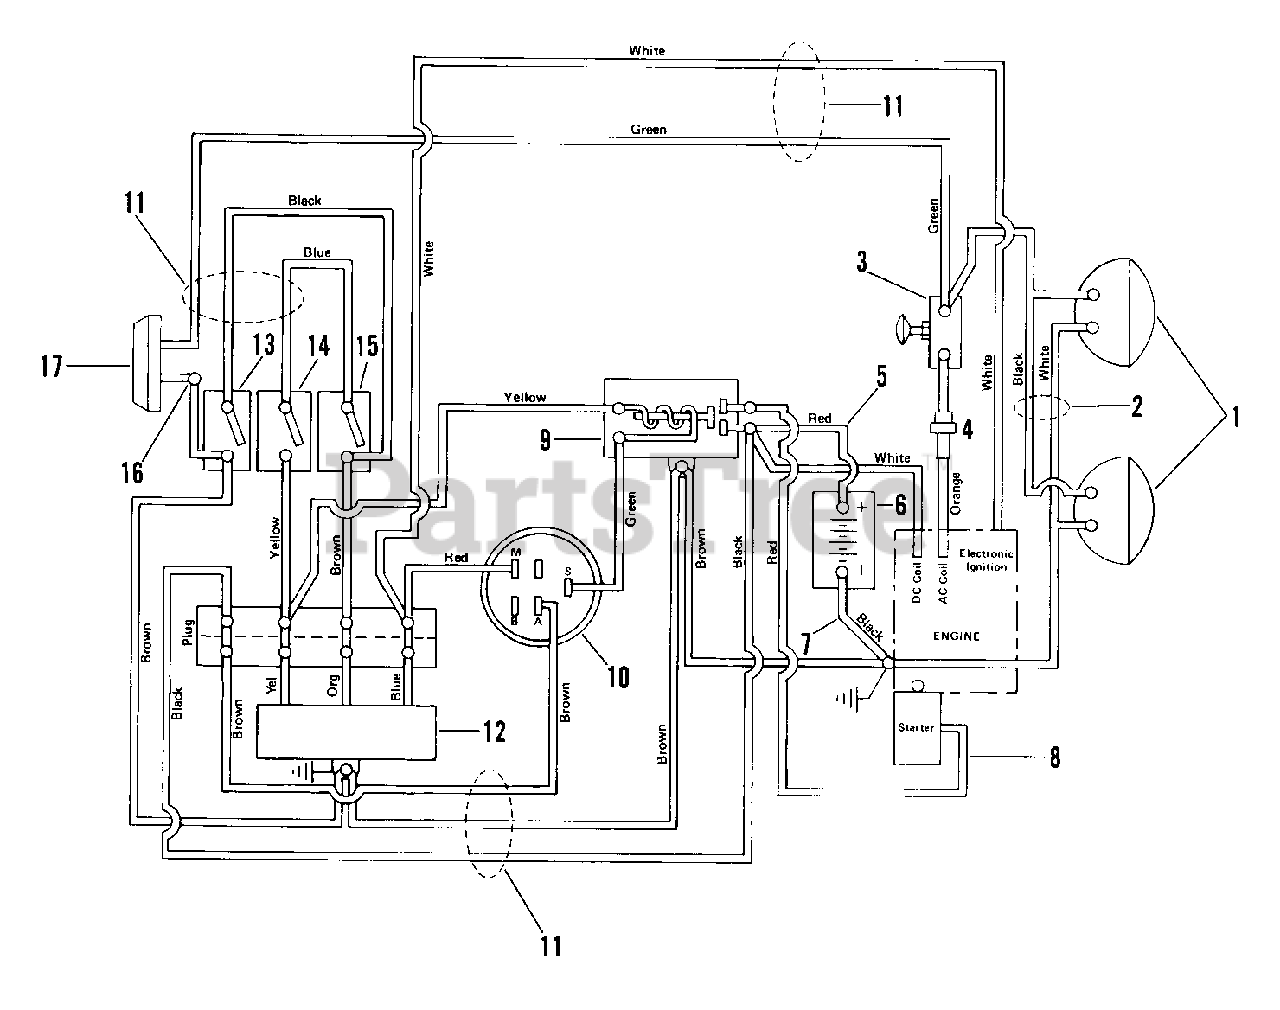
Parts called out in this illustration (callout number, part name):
1	HEAD LIGHT
2	WIRE HARNESS - HEADLIGHT
3	LIGHT SWITCH
4	6 AMP FUSE
4	15 AMP FUSE
6	BATTERY
7	CABLE-GROUND
8	CABLE STARTER
9	SOLENOID
10	IGNITION SWITCH ASSEMBLY
11	WIRE HARNESS
12	MODULE
13	SWITCH SEAT
14	SWITCH INTERLOCK
15	SWITCH-NEUTRAL START N.O.
15	SAFETY SWITCH
16	MALE DISCONNECT ADAPTER
17	TAIL LIGHT ASSEMBLY W/BULLET
